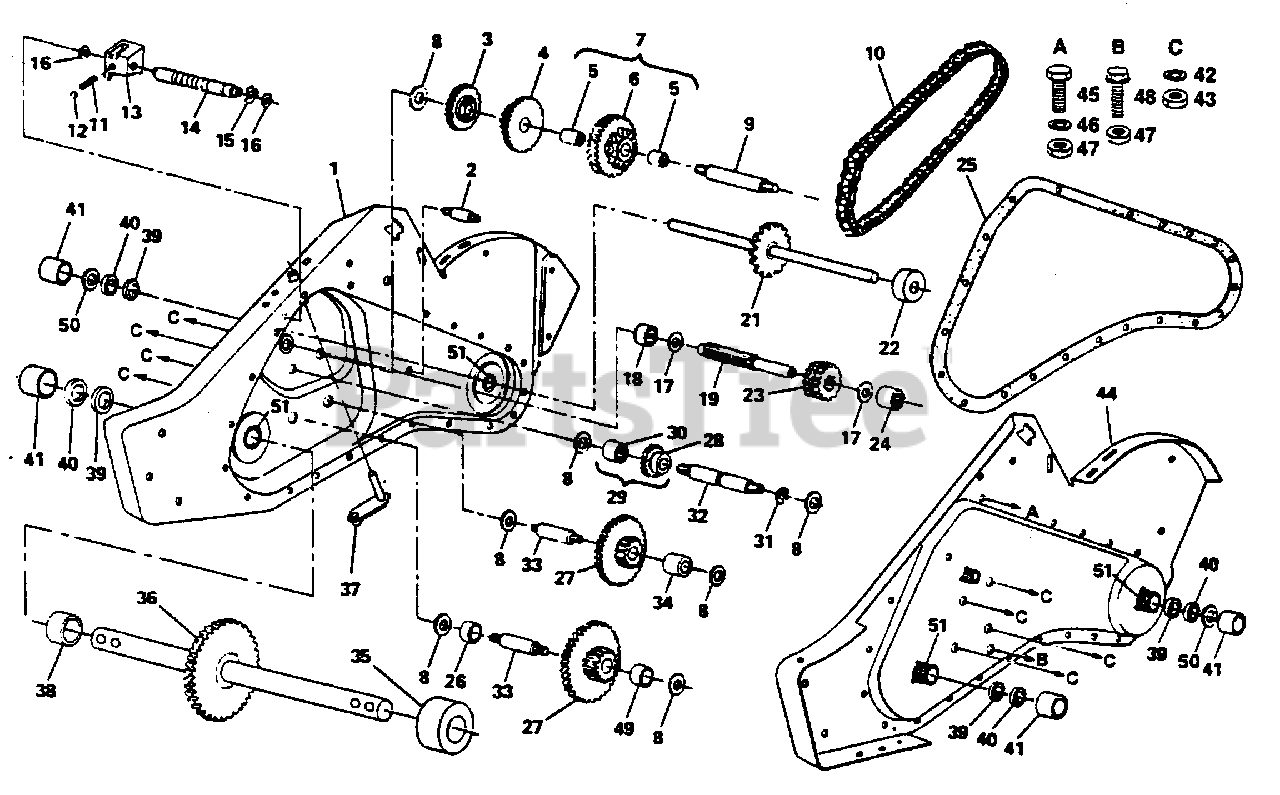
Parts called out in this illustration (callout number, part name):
1	Gearcase Assembly, R.H., with Bearing (Includes Key No. 18) (AYP part number)
2	Bolt, Upset (AYP part number)
3	Gear, Reverse (AYP part number)
4	Gear, Cluster, Red., 1st and 2nd (AYP part number)
5	Bearing, Needle (AYP part number)
6	Sprocket Assembly, Tine (AYP part number)
7	Sprocket Assembly with Bearings (Incl. Key #6 & two of Key #5) (AYP part number)
8	Washer (AYP part number)
9	Shaft, Reduction, 1st (AYP part number)
10	Chain, Roller, 60P (AYP part number)
11	Spring, Shift, Fork (AYP part number)
12	Ball, Steel (AYP part number)
13	Fork, Shift
14	Shaft, Shift (AYP part number)
15	Klip Ring (AYP part number)
16	Washer, Seal (AYP part number)
17	Race, Bearing, Thrust, 5/8 I.D. (AYP part number)
18	Bearing, Needle (AYP part number)
19	Shaft, Input (AYP part number)
21	Shaft Assembly, Tine (AYP part number)
22	Spacer 1.008 x 1-3/4 x .645 (AYP part number)
23	Pinion, Input (AYP part number)
24	Bearing, Needle (AYP part number)
25	Gasket, Gearcase (AYP part number)
26	Spacer .765 I.D. x 1.12 x 5/8 (AYP part number)
27	Gear, Cluster, Red., 2nd and 3rd (AYP part number)
28	Gear, Reverse Idler (AYP part number)
29	Gear Assembly, Reverse Idler (Includes Key Numbers 28 and 30) (AYP part number)
30	Bearing, Needle (AYP part number)
31	Klip Ring (AYP part number)
32	Shaft, Reverse Idler (AYP part number)
33	Shaft, Reduction, 2nd (AYP part number)
34	Spacer .765 I.D. x 1-1/8 x 1-3/8 (AYP part number)
35	Spacer, Ground Drive, L.H. (AYP part number)
36	Shaft Assembly, Ground (AYP part number)
37	Arm Assembly, Shift
38	Spacer, Ground Drive, R.H. (AYP part number)
39	Seal, Oil (AYP part number)
40	Seal, Ring, Rubber (AYP part number)
41	Cup, Formed (AYP part number)
42	Washer, Lock 7/16 (AYP part number)
43	Nut, Hex 7/16-20 (AYP part number)
44	Gearcase Assembly, L.H., with Bearing (Includes Key Number 24) (AYP part number)
45	Bolt, Hex Head 5/16-18 x 3/4 (AYP part number)
46	Washer, Lock 5/16 (AYP part number)
47	Nut, Hex Head 5/16-18 (AYP part number)
48	Screw, Whiz-Lock 5/16-18 x 4 (AYP part number)
49	Spacer .765 I.D. x 1.12 x 3/4 (AYP part number)
50	Ring, Spiral (AYP part number)
51	Kit, Bearing (AYP part number)
